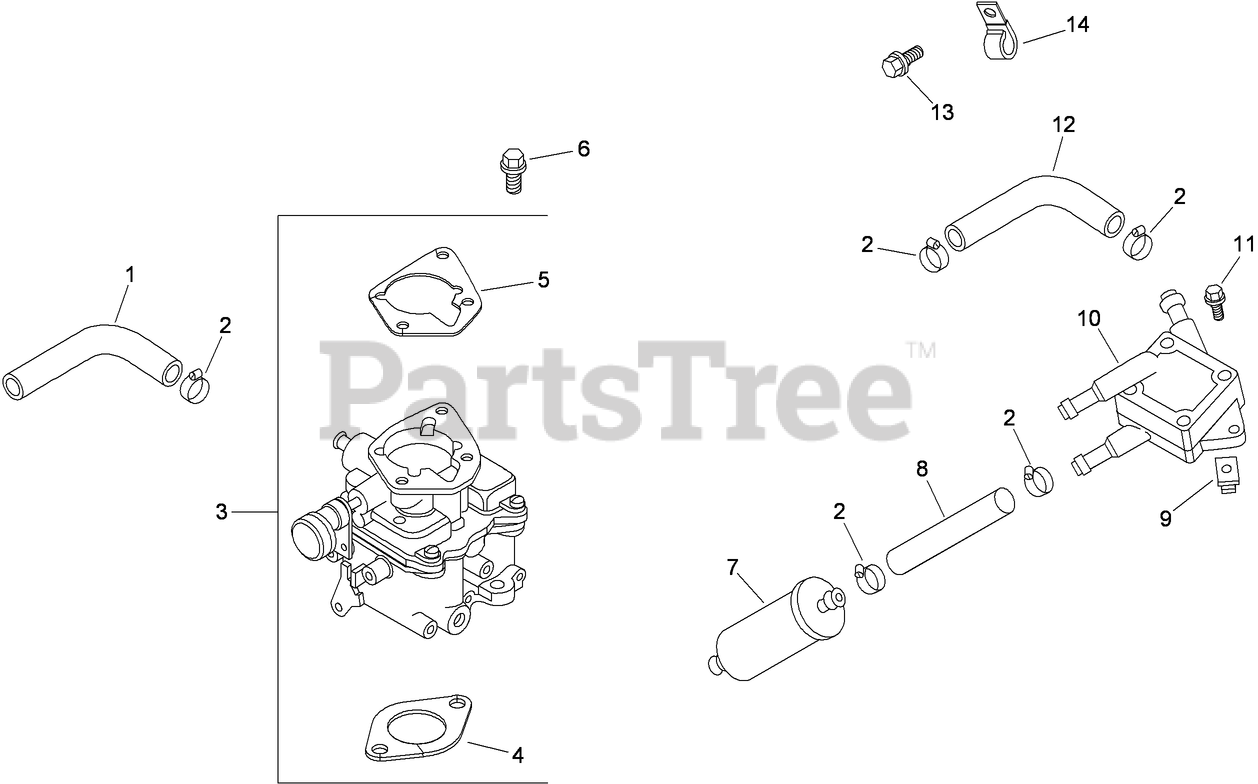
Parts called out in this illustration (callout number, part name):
1	HOSE-FUEL, LOW-PERMEATION
2	CLAMP-HOSE, SPRING (1/2)
3	Carburetor Kit (INCLUDES 4, 5)
4	Gasket-Carburetor
5	GASKET-BASE, AIR CLEANER
6	SCREW-FLANGE (M6X1.0X30)
7	Filter-Fuel
8	LINE-FUEL (24.0 CUT TO LENGTH)
9	Nut-Plastic
10	PUMP-FUEL
11	SCREW-TAP (M6X1.7X18)
12	Line-Fuel, Flexible (15.5)
13	SCREW-FLANGED, THREAD FORMING (M6X1.0X11)
14	CLIP-CABLE
